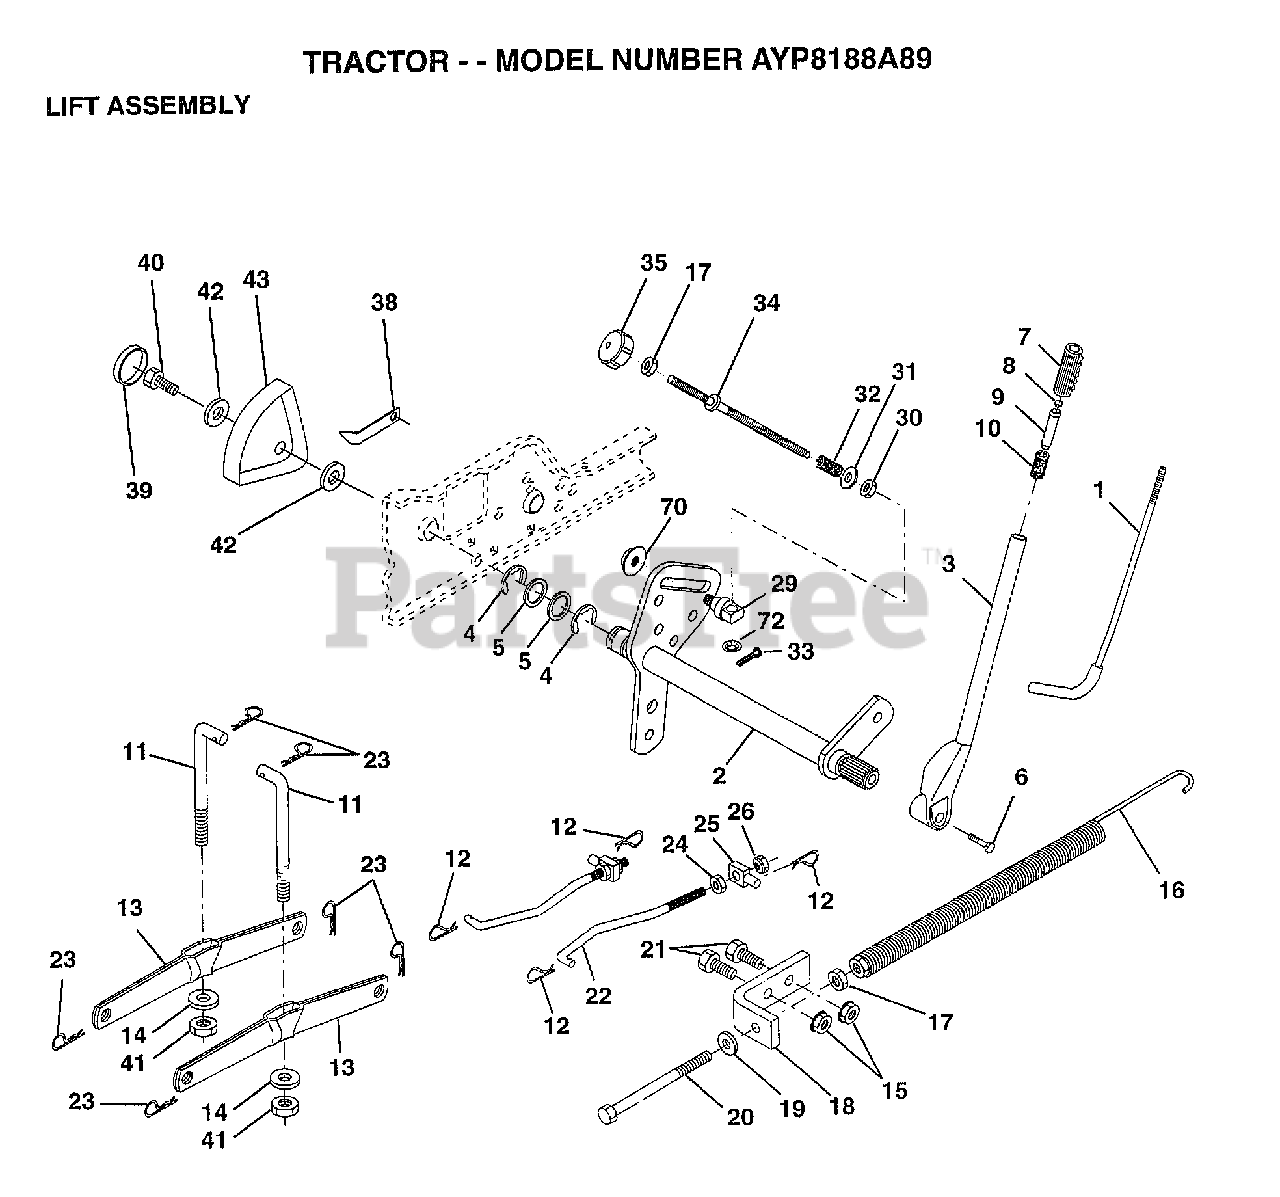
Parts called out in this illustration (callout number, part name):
1	LEVER ROD LT
2	SHAFT AMS LIFT
4	E-RING
5	WASHER
6	"BOLT,HEX"
7	GRIP HANDLE
10	SPRING T
11	LINK.LIFT.MWR.VGT
12	RETAINER SPRING
13	ARM SUSP REAR
14	BEARING PVT LH
17	NUT
18	BRACKET SPRING AS
19	WASHER
20	BOLT-ADJ SPRING T
21	BOLT
22	LINK.FRONT
24	NUT
25	TRUNION
26	NUT LTV
29	TRUNNION
30	NUT T
31	WASHER
32	SPRING.COMP.INF.H
34	ROD.ADJ.LIFT
35	KNOB INF 3/8-16
38	POINTER-INDICAT
39	"PLUG,HOLE"
40	SCREW
41	NUT.CROWNLOCK.3/8
42	WASHER
43	HEIGHT INDICATOR
70	NUT.HXFLG.LOCK.
